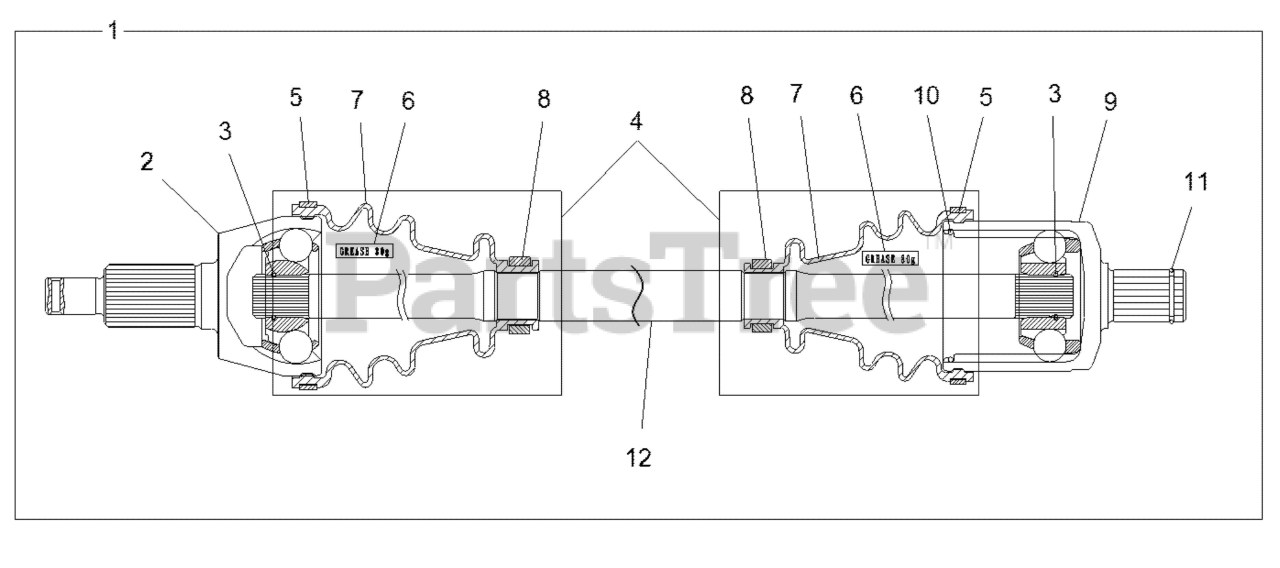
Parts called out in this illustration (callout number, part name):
1	ASM-HALF SHAFT,FRONT,LT
2	JOINT-CV,OUTER
3	CIRCLIP-1.8X22.2(PR-3011)
4	KIT-BOOT,PLUNGING JNT(PR-8062)
5	CLAMP-LARGE(PR-2019)
6	GREASE(K575/VW738)
7	BOOT(PR-0015)
8	CLAMP-SMALL(PR-0016)
9	JOINT-CV,INNER
10	CIRCLIP-2.0X61.7(PR-2016)
11	CIRCLIP-1.6X24.4(PR-2025)
12	SHAFT,23.5(PR-315)
